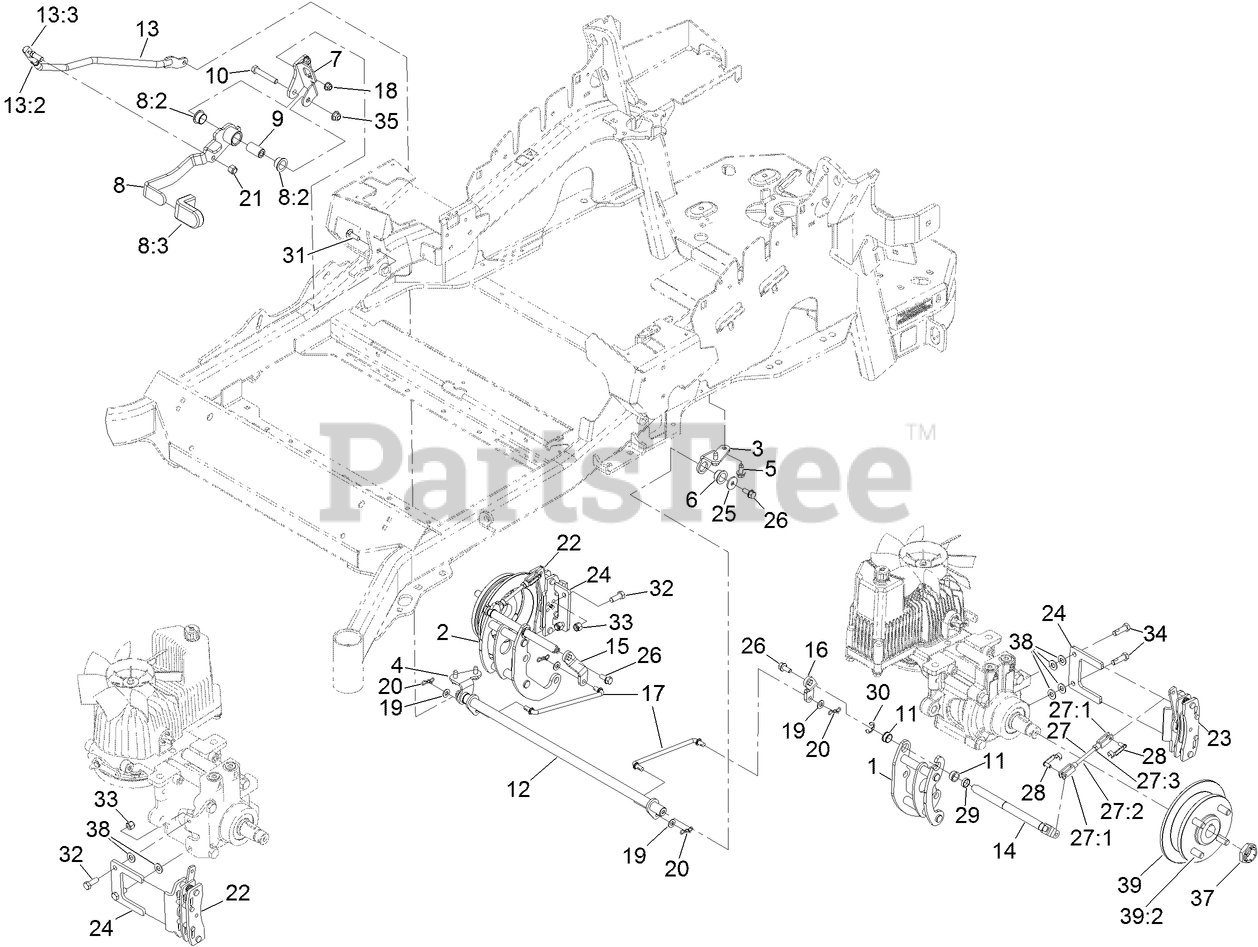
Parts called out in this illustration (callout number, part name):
1	MOUNT-BELLCRANK, LH
2	MOUNT-BELLCRANK, RH
3	MOUNT-PIVOT, LH
4	MOUNT-PIVOT, RH
5	SCREW-HWHTF
6	BUSHING-FLANGE
7	BRACKET-MOUNT
8	BRAKE LEVER ASM
8:2	BUSHING-FLANGE
8:3	GRIP-LEVER
9	HANDLE-PIVOT, BRAKE
10	SCREW-HH
11	BUSHING
12	SHAFT-CROSS
13	ASM, FRONT LINKAGE
13:2	END-TIE ROD, RH
13:3	NUT-HJ
14	BELLCRANK
15	ARM-INNER, RH
16	ARM-INNER, LH
17	WIREFORM, MID-LINK, LWB
18	NUT-HF, NI
19	WASHER-PLAIN
20	PIN-COTTER, LOCKING
21	NUT-LOCK
22	CALIPER-BRAKE, RH
23	CALIPER-BRAKE, LH
24	PLATE-MOUNT, BRAKE
25	WASHER-FLAT
26	SCREW-HHF
27	REAR LINKAGE ASM
27:2	LINKAGE, REAR
27:3	NUT-JAM
28	PIN-CLEVIS, SPRING
29	SPACER
30	E-RING
31	BOLT-CARR
32	SCREW-HH,
33	NUT-LOCK
34	SCREW-HH, PATCH,
35	NUT-HF, NI
37	LOCKNUT
38	WASHER-FLAT
39	WHEEL HUB ASM
39:2	STUD-WHEEL
